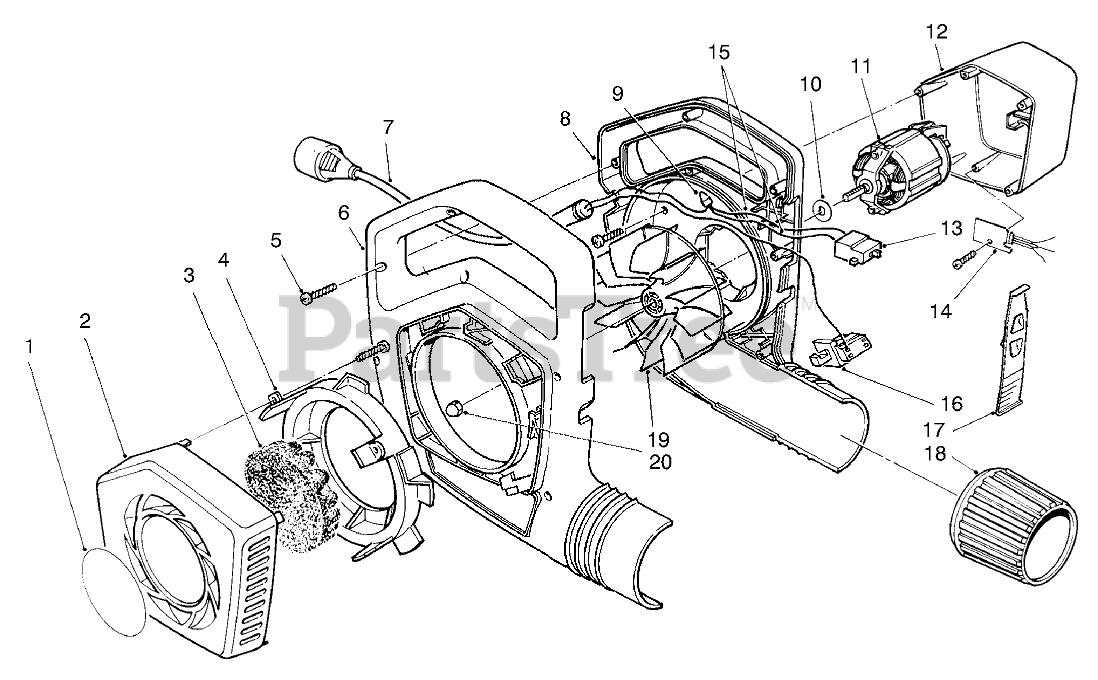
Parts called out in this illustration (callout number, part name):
1	DECAL, COVER
2	INTAKE COVER, 850 BV
3	CENTER FOAM
4	Ring-Coupling
5	Screw
6	Housing-Blower,R.H.
7	POWER SUPPLY CORD 9.5
8	BLOWER HOUSING, LH
9	Connector
10	WASHER, FAN
11	Motor-Blower
12	MOTOR COVER,850 HOTSTAM
13	Switch-2 Speed
14	DIODE ASSEMBLY
15	WIRE, 3 INCH
16	SWITCH-INTERLOCK
17	CAM SWITCH-HOT STAMPED
18	BV-OUTPUT COLLAR
19	IMPELLER, 850 BLOWER
20	NUT-HEX
